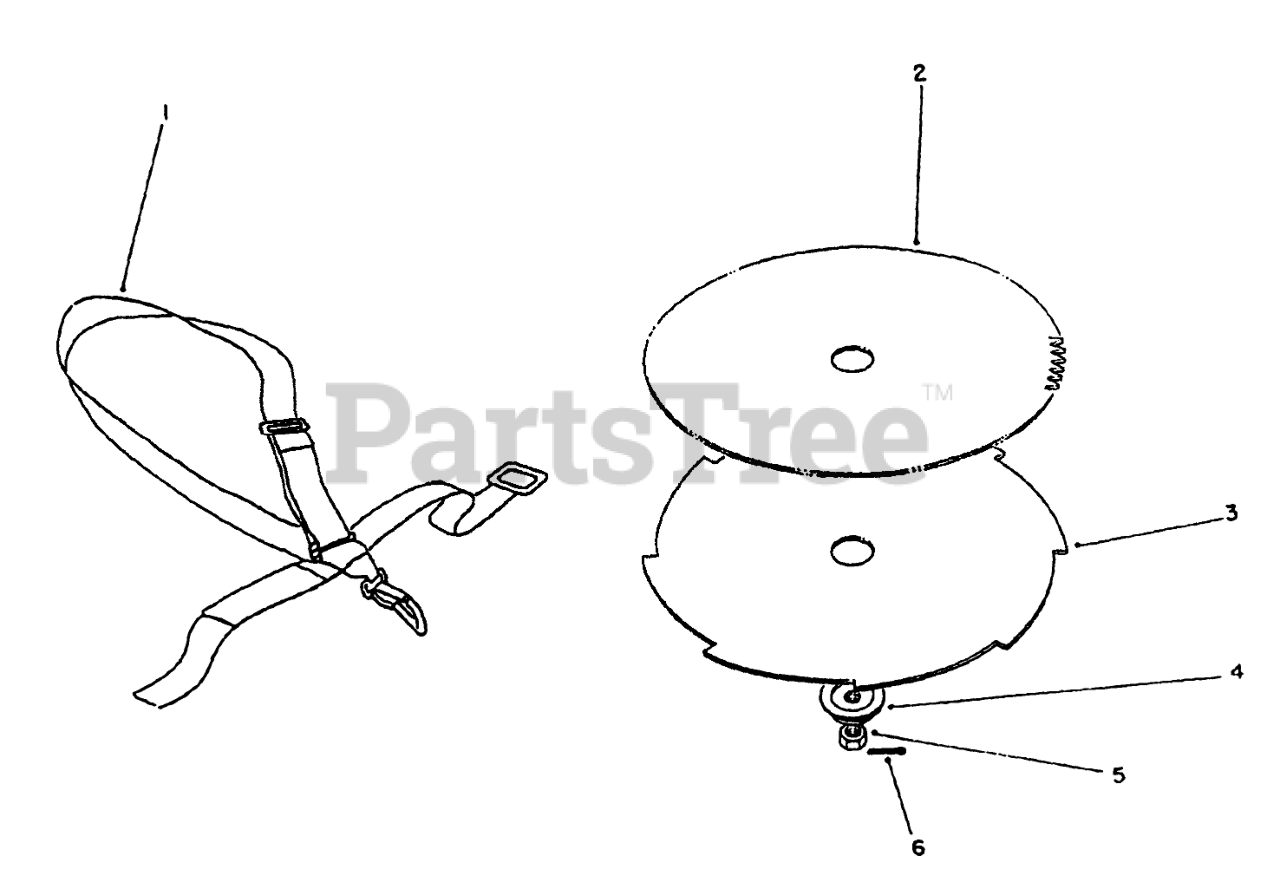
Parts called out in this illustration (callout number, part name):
1	Deluxe Harness
2	SAW BLD PKG(8", 80T)
3	BRUSH BLD PKG(8",8T)
4	Adapter-Blade
6	1/16 X 1 LG COTTER PIN
